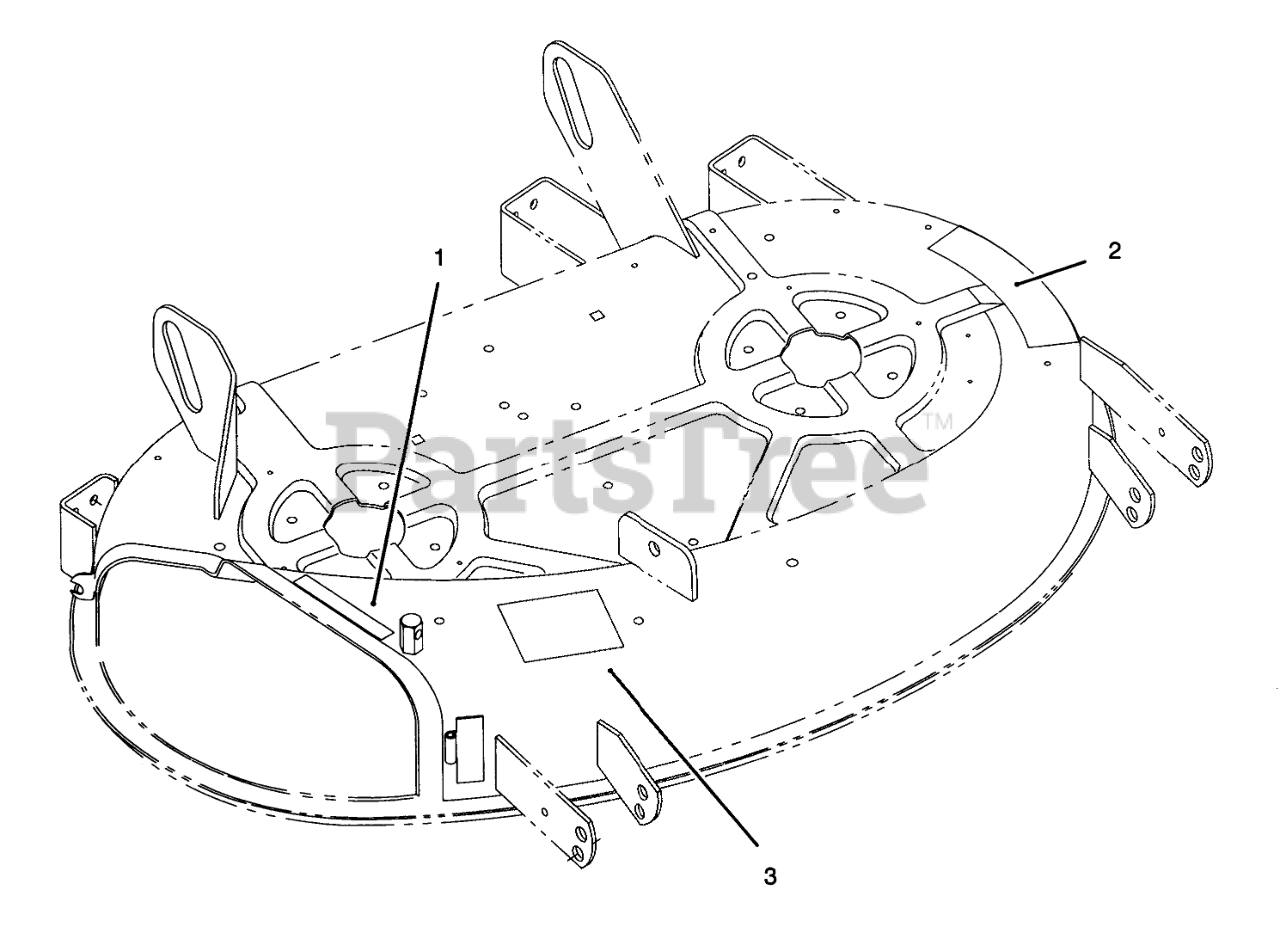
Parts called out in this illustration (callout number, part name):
1	DECAL-DANGER
2	DECAL - DANGER
3	DECAL-ROUTING, BELT
